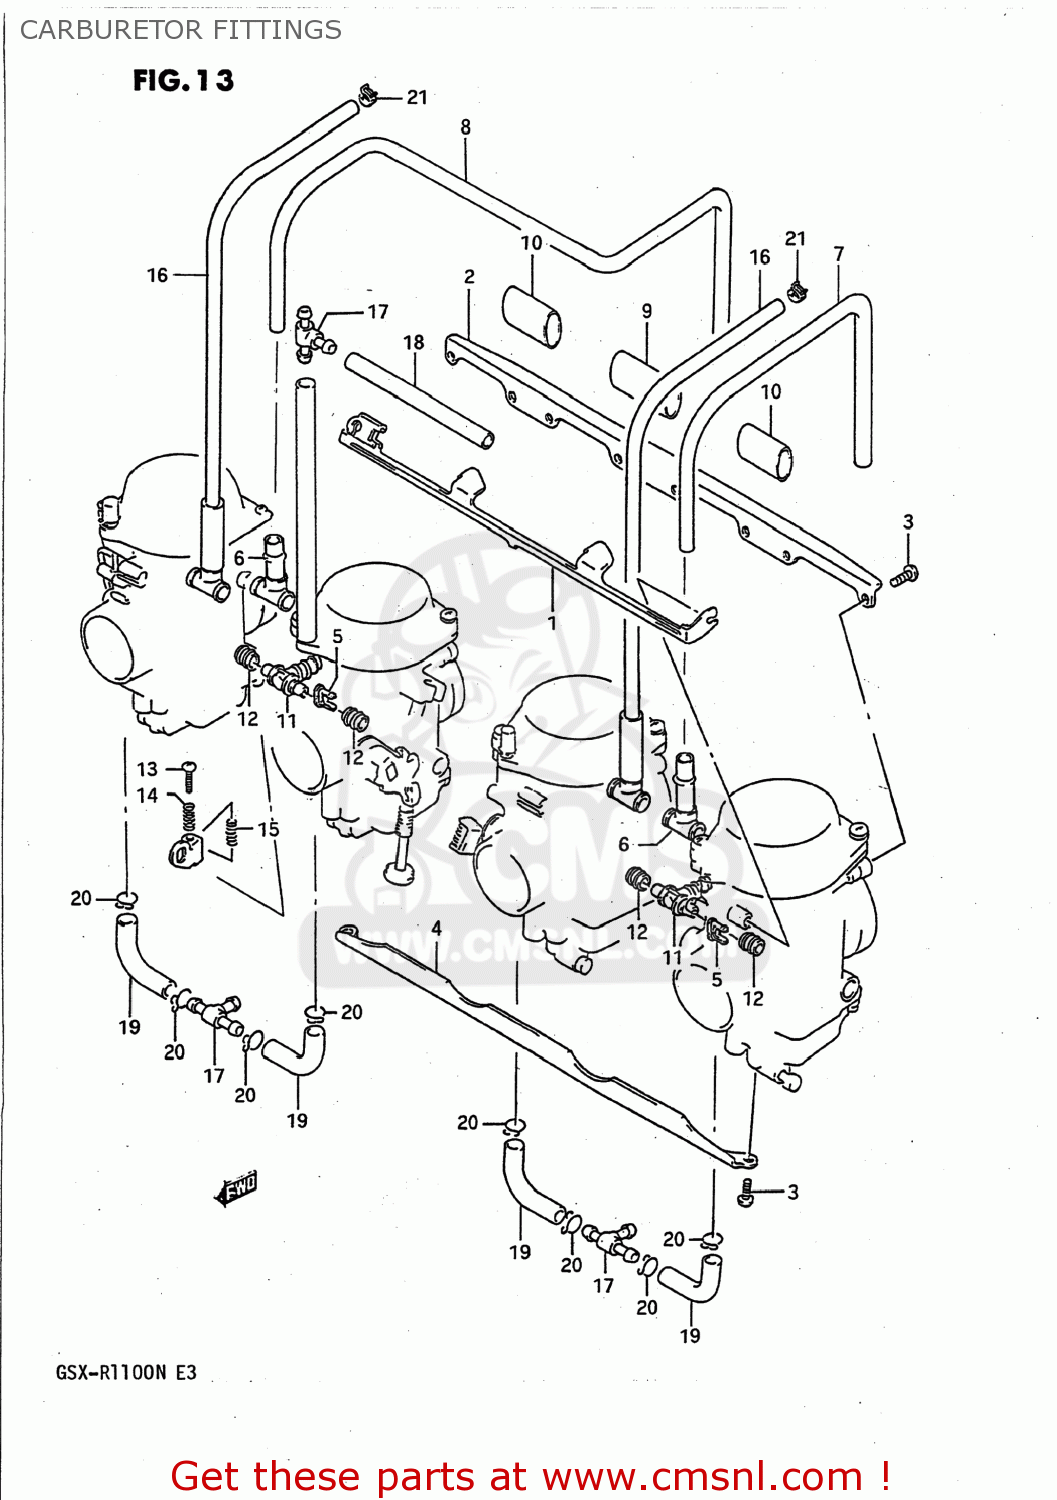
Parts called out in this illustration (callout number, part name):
1	LEVER
2	PLATE
3	SCREW
4	PLATE
5	HOLDER
6	HOSE
7	HOSE
8	HOSE
9	HOSE
10	HOSE
11	NIPPLE
12	SEAL
13	SCREW
14	SPRING
15	SPRING
16	HOSE
17	NIPPLE
18	HOSE
19	HOSE
20	CLIP
21	CLIP
